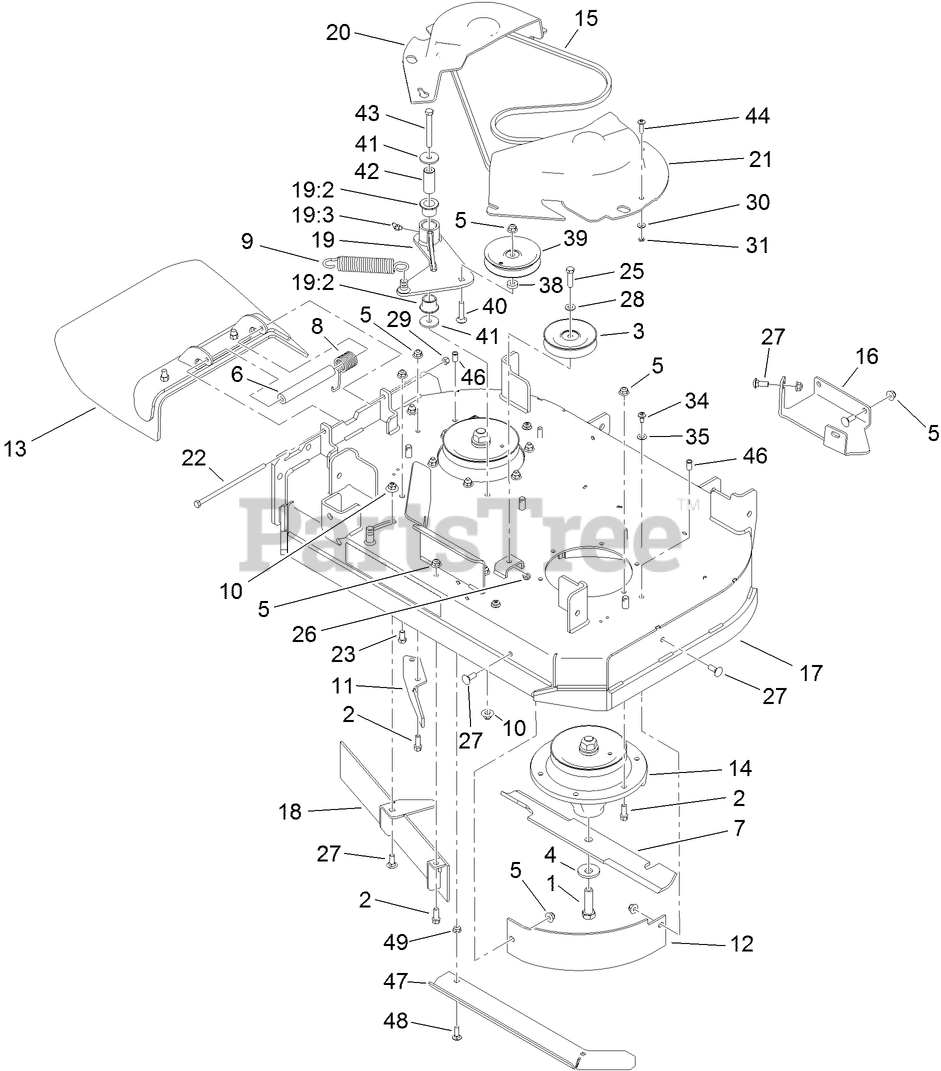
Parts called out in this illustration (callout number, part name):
1	SCREW-BLADE
2	SCREW-HWH
3	PULLEY-IDLER
4	Washer-Blade Bolt, Heavy
5	NUT-HF, NI
6	SPACER
7	BLADE-18IN, HI FLOW
8	SPRING-TORSION
9	SPRING-EXTENSION
10	NUT-FLANGE, NI
11	BAFFLE-DISCHARGE
12	BAFFLE-FRONT, LH
13	DEFLECTOR ASM
14	SPINDLE ASM
15	BELT-V
16	PLATE-SKID
17	DECK ASM
18	FRONT BAFFLE ASM
19	IDLER ARM ASM
19:2	BUSHING
19:3	FITTING-LUBE, 45 DEG
20	COVER-BELT, RH
21	COVER-BELT, LH
22	SCREW-HH
23	SCREW-HH
25	SCREW-HH
26	NUT-LOCK, NI
27	BOLT-CARR
28	WASHER-FLAT
29	NUT-LOCK, NI
30	WASHER-FLAT
31	NUT-RETAINER
34	SCREW-SHOULDER
35	WASHER-THRUST
38	SPACER
39	PULLEY-IDLER
40	SCREW-CARR
41	WASHER
42	SPACER-PLAIN
43	SCREW-HH
44	SCREW-TTH
46	INSERT-NUT
47	EXTENDER-DECK
48	BOLT-CARR
49	NUT-HF, NI
